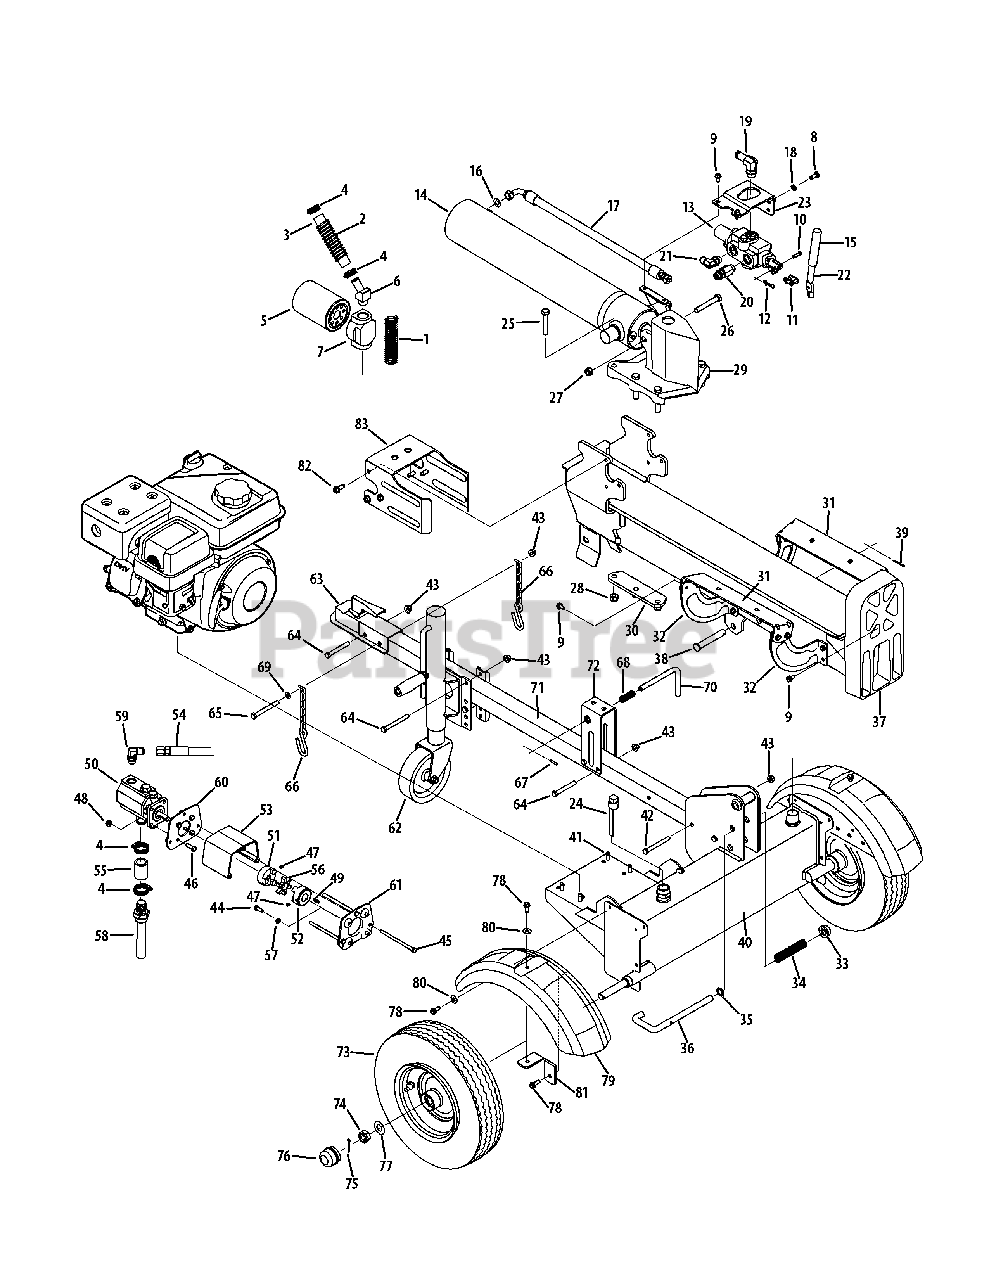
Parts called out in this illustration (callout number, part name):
1	Hose Guard
2	Hose Guard
3	Return Hose
4	Hose Clamp
5	Oil Filter
6	Hydraulic Fitting
7	Filter Housing
8	Hex Screw, 3/8-16 x .75
9	Hex Washer Screw, 5/16-18 x .750
10	Clevis Pin, .25 x 1.00
11	Valve Handle Link
12	Cotter Pin
13	Log Splitter Valve
14	Hydraulic Cylinder, 4.5 x 24
15	Grip, .625
16	Hydraulic O-Ring
17	Hydraulic Hose
18	Lock Washer, 3/8
19	Hydraulic Fitting, 7/8 x .75
20	Hydraulic Fitting, 3/4
21	Hydraulic Fitting, 3/4 x 13/16
22	Hydraulic Valve Control
23	Valve Bracket
24	Plug w/ Dipstick
25	Hex Screw, 1/2-20 x 2.75
26	Hex Screw, 1/2-13 x 3.25
27	Hex Lock Nut, 1/2-13
28	Hex Lock Nut, 1/2-20
29	Log Splitter Wedge
30	Log Splitter Wedge Plate
31	Log Tray Bracket
32	Log Splitter Tray Bracket
33	Push Cap, 5/8
34	Compression Spring, .625 x 4.0
35	Flat Washer, .635 x .930 x .060
36	Beam Lock Rod
37	Beam Assembly
38	Clevis Pin, .625 x 4.25
39	Cotter Pin, 1/8 x 1.25
40	Tank Assembly
41	Hex Washer Screw, 3/8-16 x 1.000
42	Hex Screw, 3/8-16 x 3.50
43	Flange Lock Nut, 3/8-16
44	Hex Screw, 5/16-24 x .75
45	Hex Screw, 5/16-18 x 4.00
46	Hex Screw, 5/16-18 x 1.00
47	Set Screw, 1/4-20 x .38
48	Flange Lock Nut, 5/16-18
49	Square Key, 3/16 x .75
50	Gear Pump
51	Coupling, .500
52	Coupling, .750
53	Coupling Shield Spacer
54	Hydraulic Hose
55	Input Hose, 1.0
56	Spider Bushing
57	Lock Washer, 5/16
58	Inlet Filter
59	Hydraulic Fitting
60	Rear Coupling Support Bracket
61	Front Coupling Support Bracket
62	Adjustable Stand Assembly
63	Hitch Coupling Assembly
64	Hex Screw, 3/8-16 x 3.00
65	Hex Screw, 3/8-16 x 3.50
66	Tow Chain
67	Spirol Pin, 3/16 x 1.00
68	Compression Spring, .66 x 1.9
69	Flat Washer, .375 x .738 x .063
70	Latching Rod
71	Tongue Tube, 2.0 x 2.0
72	Tongue Latch
73	Complete Wheel, 16.0 x 4.8 x 8.0
73	Rim, 3.75 x 8.0
73	Tire, 16 x 4.80-8
73	Inner Tube, 4.80/4.00-8
73	Grease Retainer
73	Bearing
74	Slotted Nut, 3/4-16
75	Cotter Pin, 5/32 x 1.25
76	Hub Cap
77	Flat Washer, .760 x 1.50 x .030
78	Hex Washer Screw, 5/16-18 x 1.000
79	Fender
80	Thrust Washer, .343 x .880 x .062
81	Fender Mount Bracket
82	Hex Washer Screw, 3/8-16 x 1.000
83	Dislodger Bracket
